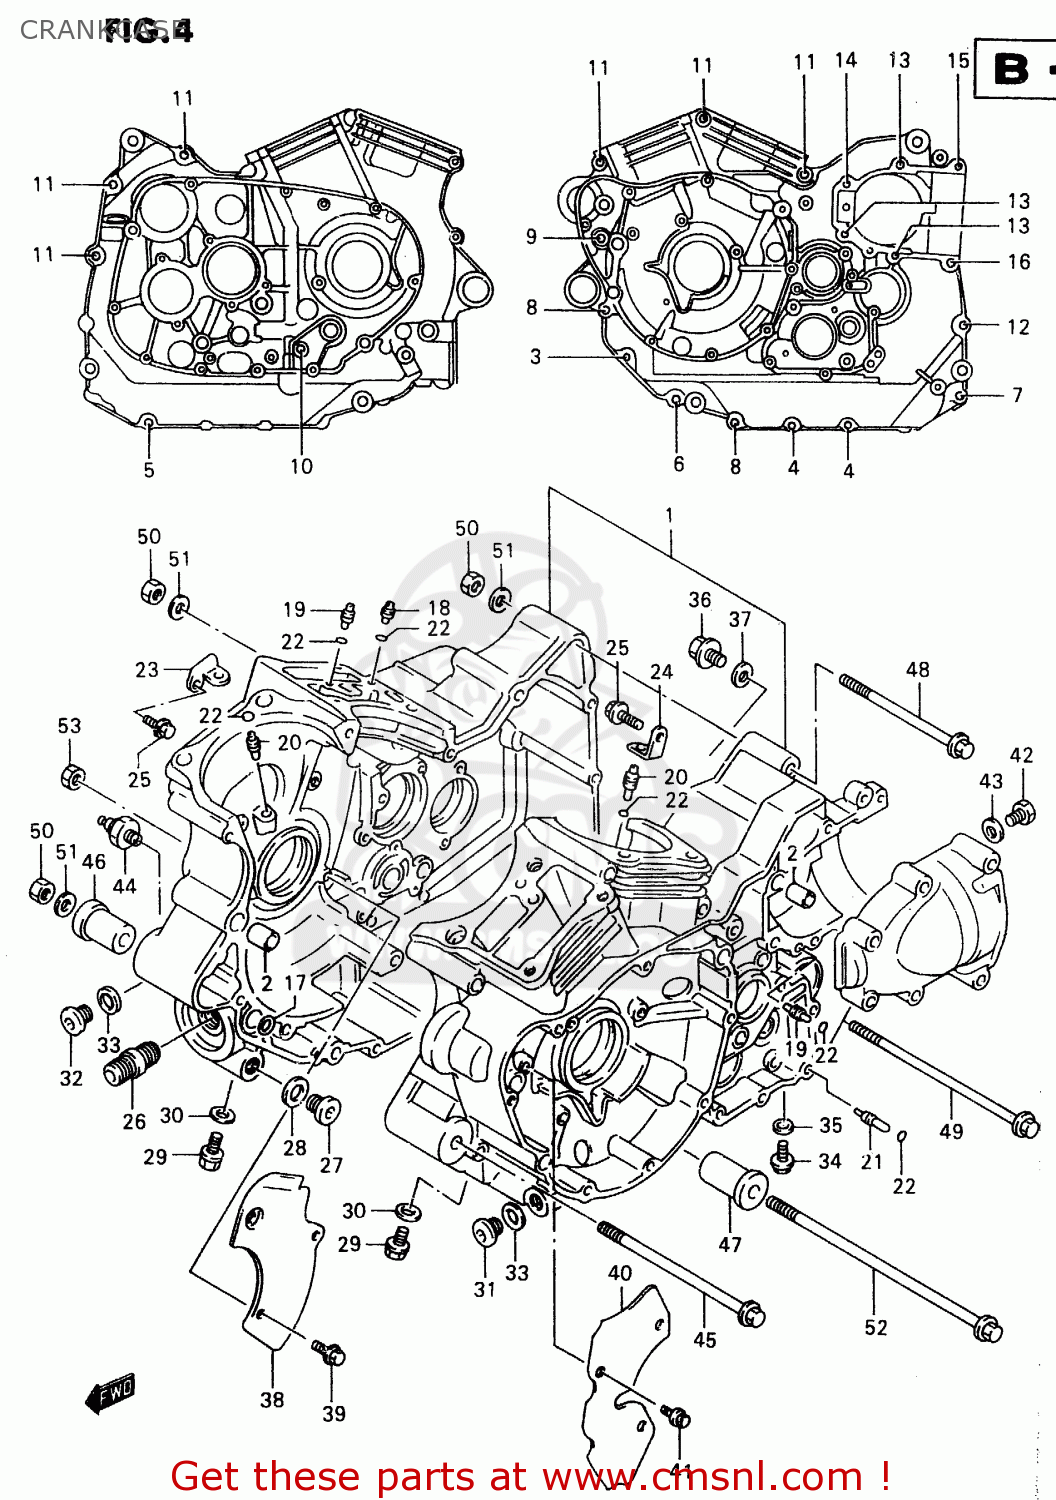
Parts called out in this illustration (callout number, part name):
1	CRANKCASE SET
2	PIN(8.4X11X20)
3	BOLT, HYDRAULIC UNIT NO.2
4	BOLT
5	BOLT
6	BOLT
7	BOLT
8	BOLT (8X70)
9	BOLT
10	BOLT(8X115)
11	BOLT(8X95)
12	BOLT (8X80)
13	BOLT
14	BOLT
15	BOLT
16	BOLT
17	O RING(D:1.9,ID:12.6)
18	JET(2.2)
19	JET,AIR(14)
20	JET,PISTON COOLING(0.8)
21	JET,MISSION OIL(1.4)
22	O RING(D:1.2,ID:4)
23	PLATE,PISTON JET FR
24	PLATE,PISTON JET RR
25	BOLT
26	UNION,OIL STAND
27	PLUG
28	GASKET(16X22X2) (NAS)
29	BOLT
30	GASKET(8.2X14X1).6 (NAS)
31	PLUG,14X12
32	PLUG(14X11.5)
33	GASKET(13.8X18.8X4.8) (NAS)
34	BOLT
35	GASKET(5.8X11X1.2) (NAS)
36	PLUG(12X10)
37	GASKET(12.1X16.2X3.7) (NAS)
38	PLATE,OIL SEPARATOR
39	BOLT(6X12)
40	PLATE,OIL SEPARATOR FR
41	BOLT
42	PLUG, OIL DRAIN
43	GASKET(12.1X16.2X3.7) (NAS)
44	SWITCH ASSEMBLY,OIL PRESSURE
45	BOLT(10X205)
46	SPACER,ENG MTG
47	SPACER,ENGINE MOUNT(L27)
48	BOLT(10X140)
49	BOLT(10X160)
50	NUT
51	WASHER
52	BOLT(10X265)
53	NUT
